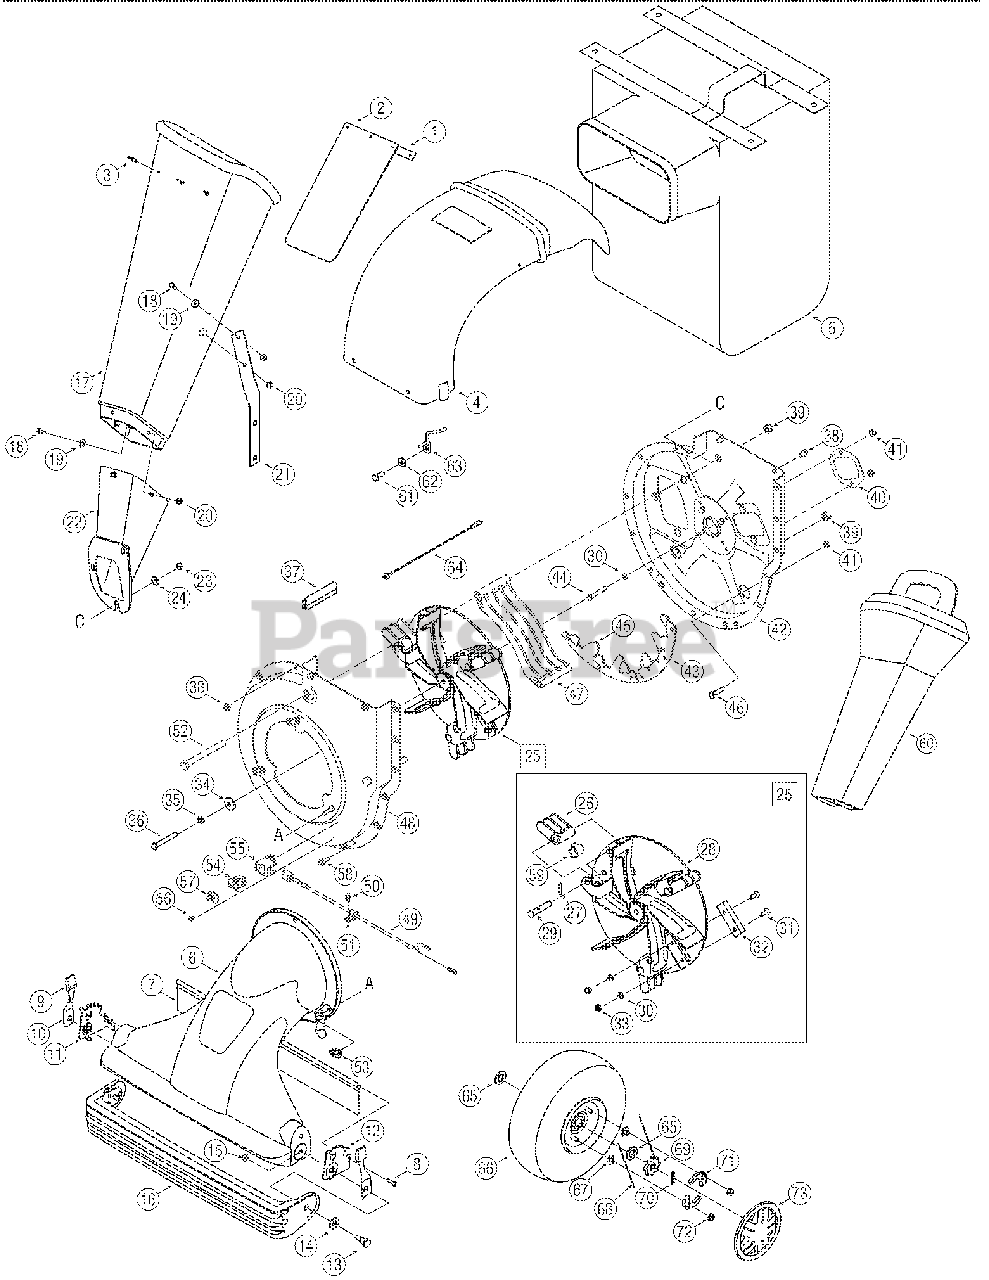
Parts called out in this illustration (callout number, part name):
1	Chute Flap Strip
2	Chute Flap
3	Pop Rivet
4	Discharge Chute
5	Bag
6	Nozzle Assembly
7	Nozzle Flap
9	Height Adjustment Knob
10	Spring Lever
13	Shoulder Screw
14	Flat Washer.510 x 1.12 x.060
15	Hex Flange Lock Nut 3/8-16
16	Door Assembly
17	Chipper Chute
18	Hex Cap Screw 1/4-20 x.620
19	Flat Washer.28 ID x.74 OD
20	Hex Lock Nut 1/4-20
24	Belleville Washer,.340ID x.872OD
25	Impeller Assembly: Complete
26	Flail Blade
27	Spiral Pin
28	Impeller Assembly
29	Clevis Pin
30	Lock Washer 5/16
31	Cap Screw 5/16-24 x 1.0
32	Chipper Blade
33	Hex Lock Nut 5/16-24
34	Flat Washer.406 x 1/1/4
35	Lock Washer 3/8
36	Hex Cap Screw 3/8-24 x
37	Rubber Seal
38	Hex Washer Screw 5/16-18
39	Hex Lock Nut 1/2-13
41	Hex Flange Lock Nut 5/16-18
44	Hex Cap Screw 5/16-18 x 2
46	Hex Cap Screw 5/16-18 x.75
47	Discharge Screen
49	Wire Harness
50	TT Screw 1/4-14 x 0.625"
52	Hex Cap Screw 1/2-13 x 5.
53	Knob 5/16-18
54	Switch
55	Safety Switch Mounting Cover
56	Hex Washer Screw
57	Switch Cover
58	LD Screw 5/16-18 x 0.75"
59	Retaining Pin Clip
60	Tamper Plug
61	Hex Cap Screw 5/16-24 x.75
62	Flat Washer.344 x.75 x.12
63	Belt Keeper
64	Adapter Harness Assembly
65	Flat Washer 5/8 ID x 1.0
66	Wheel Complete 10 x 4 x
67	Hex Nut 1/4-20
68	Plastic Spring Ratchet
69	Wheel Ratchet 1.62 OD x.5
70	Cotter Pin
71	Pawl LH.345 ID
71	Pawl RH.345 ID
72	Hex Flanged Lock Nut 1/4-20
